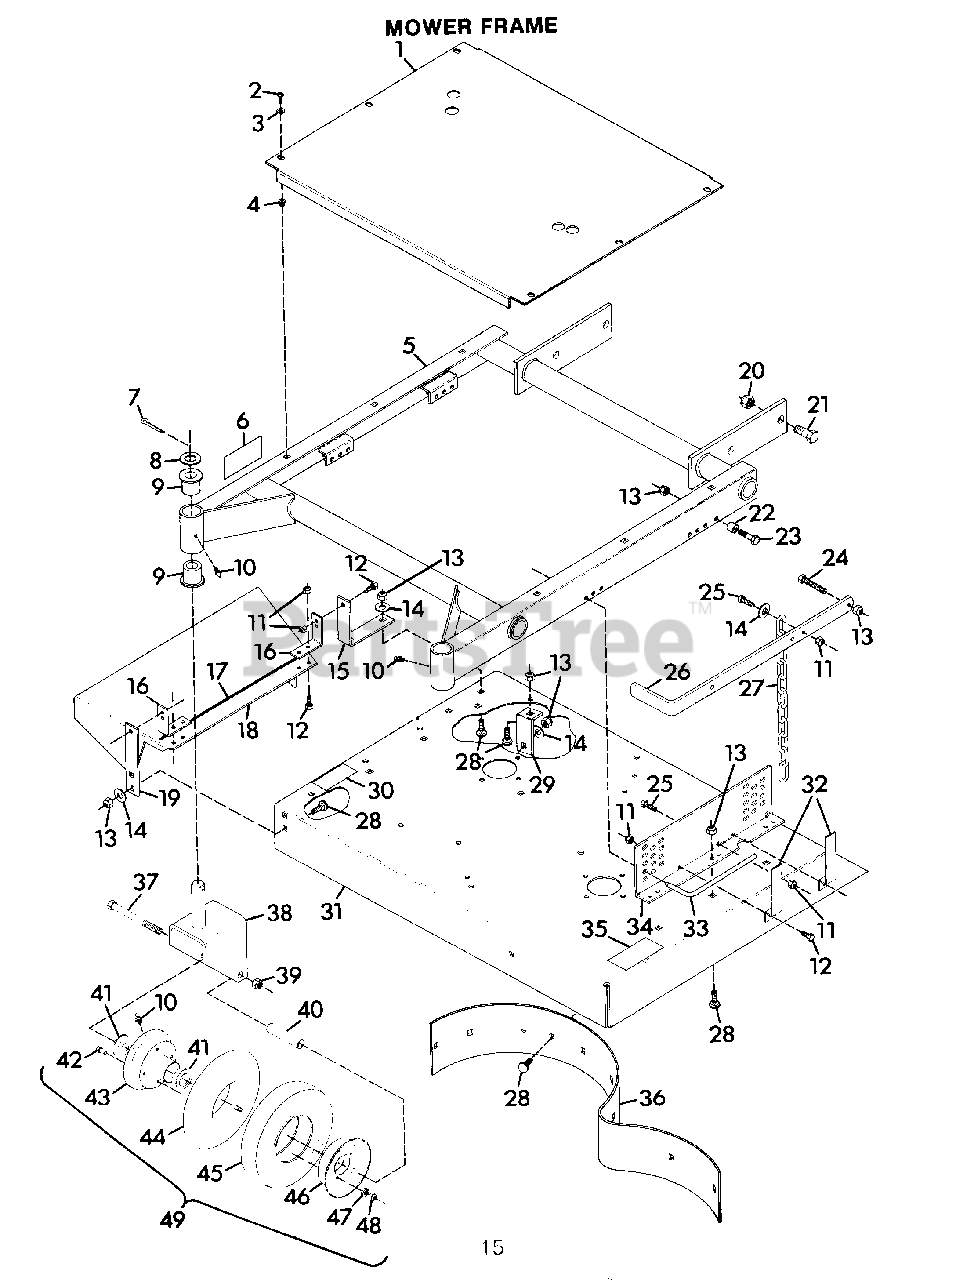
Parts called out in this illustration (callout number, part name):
1	GUARD, MOWER BELT
2	SCREW, TAPPING 1/4-20X.625 P/HD
3	WASHER, FLAT .281X.625X.065
4	GROMMET, PLASTIC
5	WELDMENT, MOWER FRAME
6	DECAL, DANGER HAND
7	PIN, COTTER .187X1.50
8	RACE, BEARING THRUST
9	BUSHING, PIVOT
10	FITTING, LUBE 1/4-28
11	NUT, LOCK 5/16-18
12	BOLT, HEX 5/16-18X.75
13	NUT, LOCK 3/8-16
14	WASHER, FLAT .406X.812X.065
15	BRACKET
16	BRACKET
17	STRIPE
18	CHUTE, DISCHARGE
19	BRACKET
20	NUT, LOCK 5/8-11
21	BOLT, HEX 5/8-11X1.50
22	BUSHING .391X.622X.670
23	BOLT, HEX 3/8-16X1.50
24	BOLT, HEX 3/8-16X2.00
25	BOLT, HEX 5/16-18X1.00
26	BAR, LIFT
27	CHAIN, HEIGHT ADJUSTMENT
28	BOLT, 3/8-16X1.00 RD HD SQ NK
29	BRACKET
30	DECAL, WARNING EYE
31	WELDMENT, 36" R.D. DECK
32	TAB, PIN LOCKING
33	PIN, MOWER LOCKING
34	BRACKET, MOWER SUPPORT
35	DECAL, DANGER FOOT
36	SCROLL
37	BOLT, HEX 1/2-13X5.00
38	WELDMENT, CASTER FORK
39	NUT, LOCK 1/2-13
40	BUSHING, WHEEL .520X.750X3.312
41	BEARING, GAUGE WHEEL
42	BOLT, HEX 3/8-24X.75
43	WHEEL, HALF WITH TUBE
44	TUBE, INNER
45	TIRE, GAUGE WHEEL
46	WHEEL, HALF PLAIN
47	WASHER, LOCK 3/8 SP HEAVY
48	NUT, HEX 3/8-24
49	WHEEL, GAUGE
NS	BRACKET, MOWER SUPPORT
NS	DECAL, GRAVELY LOGO
NS	DECAL, PRO-36 R.D.
